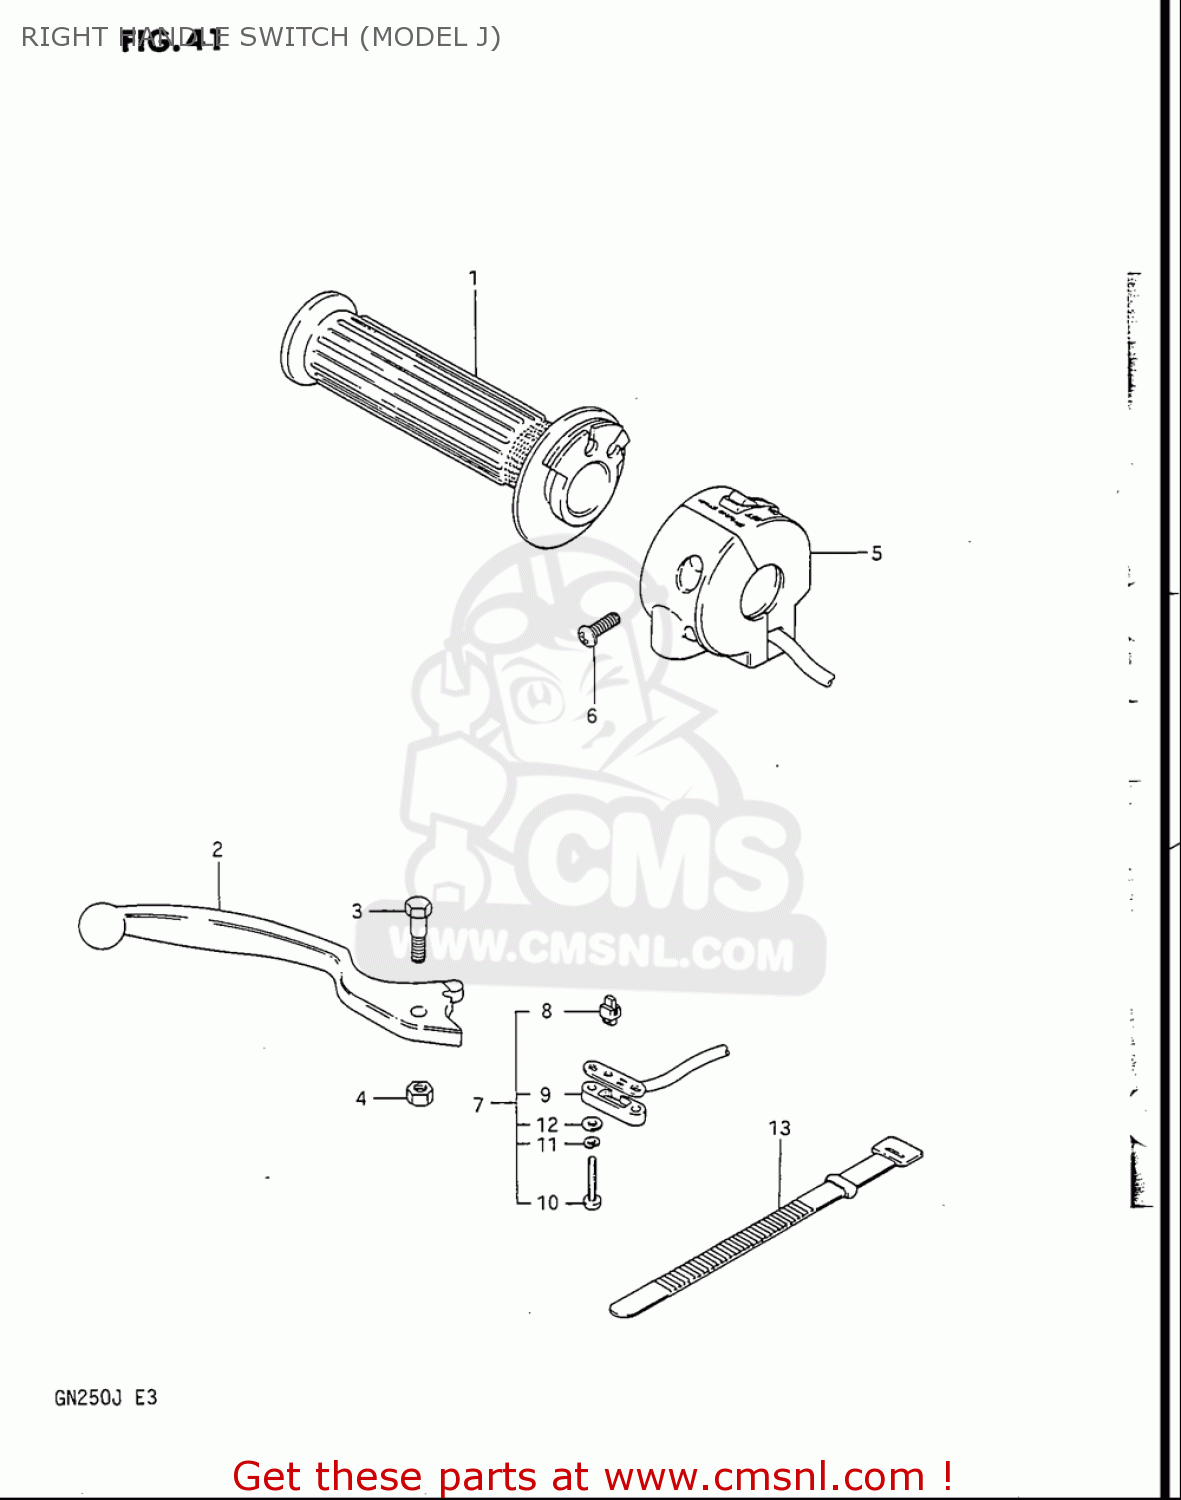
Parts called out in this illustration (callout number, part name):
1	GRIP,THROTTLE
2	LEVER,BRAKE
3	BOLT,LEVER PIVOT
4	NUT
5	SWITCH ASSY,HANDLE,R
6	SCREW(5X14)
7	SWITCH ASSY,STOP
8	CONTACT,SWITCH
9	COVER,FR BK TERMINAL BASE
10	SCREW
11	WASHER,LOCK
12	WASHER
13	CLAMP(L:120)
